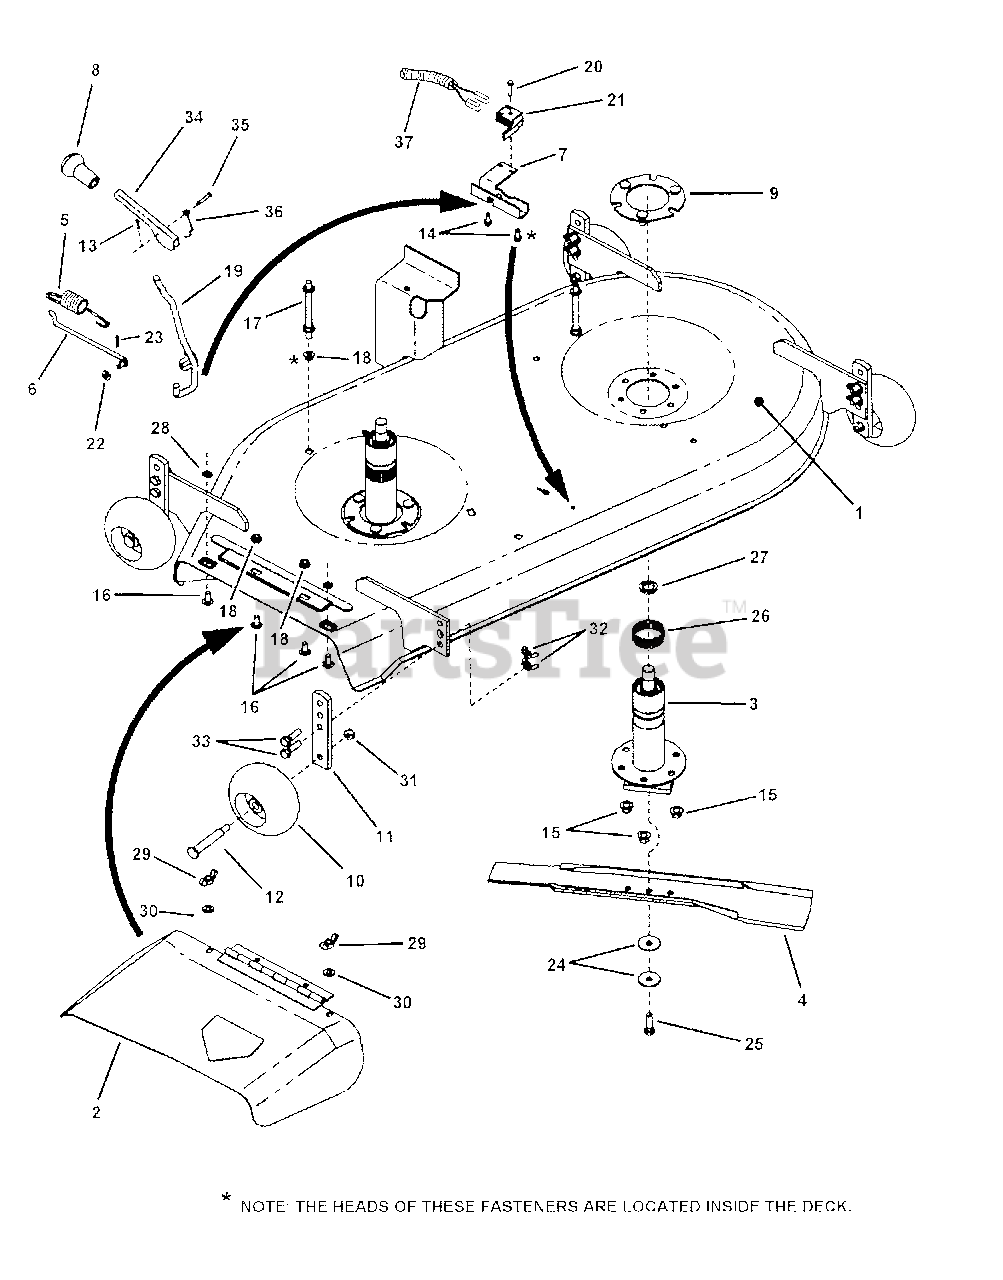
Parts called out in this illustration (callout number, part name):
1	42" DECK WELDMENT, Anti-Scalp
2	ASSEMBLY, Side Chute (incl. decal 26831)
3	ASSEMBLY, Spindle
4	BLADE, 21" Standard Lift
5	SPRING, Blade Handle
6	ROD, Idler Control
7	MOUNT, Handle/Switch
8	GRIP, Handle
9	ASSEMBLY, Spindle Ring
10	WHEEL, Gage
11	POST, Anti-Scalp
12	SHOULDER BOLT, 3/8-16 x 2.62 Hex Head
13	PIN, 3/32 x 1/2" Cotter
14	SCREW, 1/4-20 x 5/8" Hex Washer Head Self-Tap
15	NUT, 3/8-16 Hex Flange Lock
16	BOLT, 5/16-18 x 3/4" Short Square Neck Carriage, GR 5
17	STANDOFF, 3-1/2" (5/16-18 & 3/8-16 threads)
18	NUT, 3/8-16 Hex Flange Lock
19	WELDMENT, Blade Engagement Handle
20	SCREW, #10-32 x 1" Hex Washer Head Self-Tap
21	SWITCH, Deck Interlock (NO)
22	WASHER, 1/4" Flat
23	PIN, 3/32 x 3/4" Cotter
24	WASHER, 13/32" I.D. Cone
25	SCREW, 3/8-24 x 1-1/4 Hex Head Cap GR 5
26	TOLERANCE RING, 2"
28	RETAINER, 5/16" Bolt
29	WING NUT, 5/16-18
30	WASHER, 5/16" Flat
31	NUT, 3/8-16 Hex Center Lock
32	WING-NUT, 3/8-16 Nyloc
33	SCREW, 3/8-16 x 1-1/4" Hex Head Cap, GR 5
34	HANDLE, Blade Engagement
35	PIN, 3/16 x 1" Clevis
36	SPRING, Torsion
37	DECK WIRE
